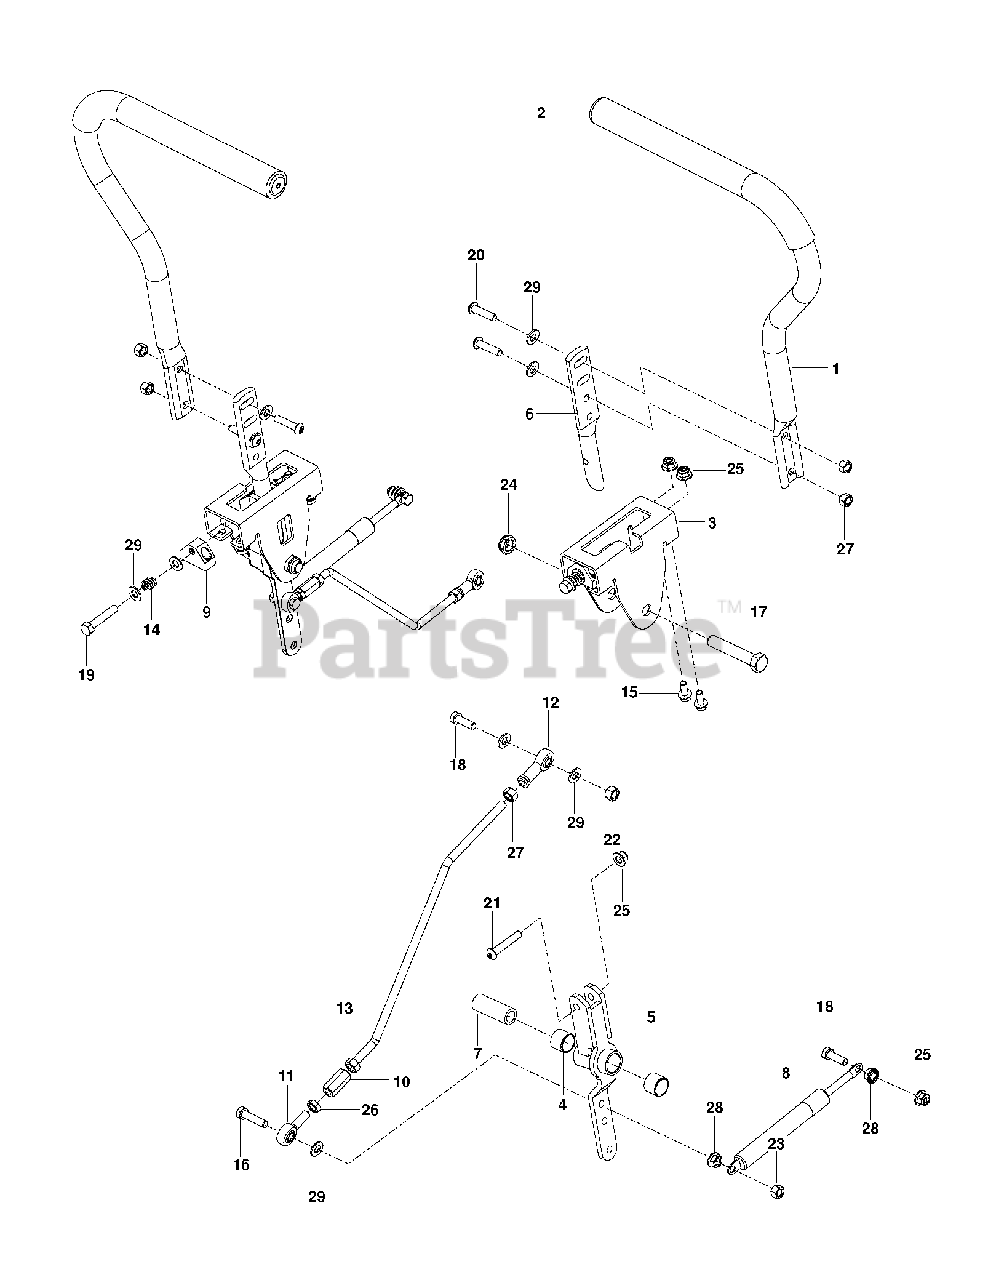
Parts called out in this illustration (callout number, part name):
1	Control Tube, RZ
2	GRIP, DRIVE LEVER
3	Narrowslot Control Bracket, Black
5	Control Weldment.Rz
6	LEVER.HANDLE MOUNT
7	Pivot Control Spacer
9	Tracking Control Block, ZTR
10	ROD END COUPLER
11	ROD END LH
12	RH ROD END
13	Motion Control Rod
15	HHFS 5/16-18 X 3/4
17	Hex Capscrew, 1/2-13 X 2-3/4 Gd 5 Zd
19	HEX BOLT
20	SCREW.BUTTHEAD.5/16-18X1-1.25
21	Buttonhead Screw, 5/16-18 X 1-3/4
22	5/16-18 THIN PROF NY
23	NUT.71038.31-18.HEX.NYLOCK
24	NUT 1/2-13 HEX JM NYL
25	5/16-18 NYLOC FLANGE NUT
26	NUT 5/16-24 HEX JAM LH GR 5 ZD
27	NUT 5/16F
28	NUT 5/16C WHIZ
29	WASHER
